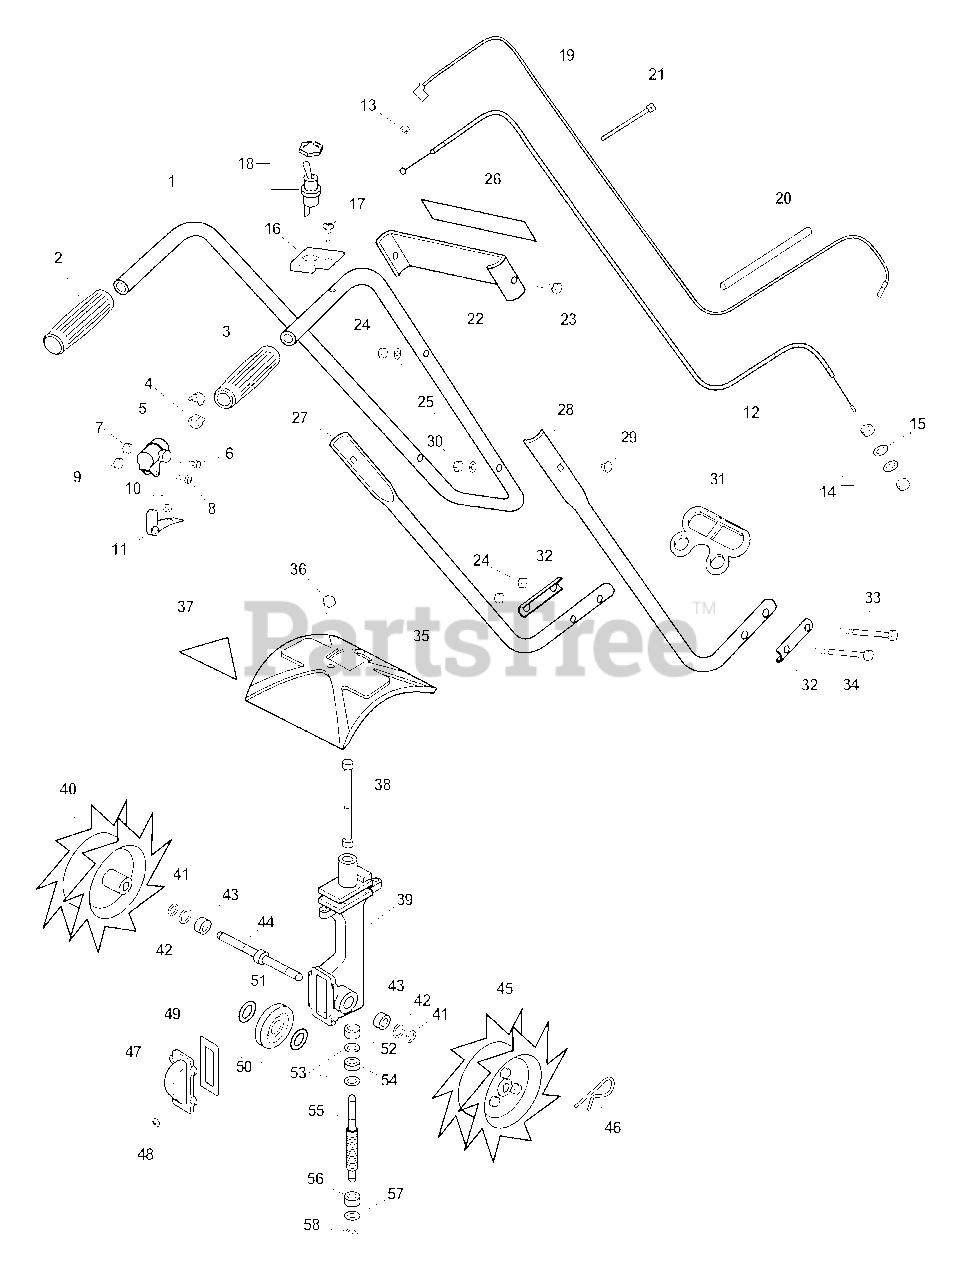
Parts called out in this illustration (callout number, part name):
1	HANDLE, UPPER
2	GRIP, HANDLE
3	GRIP, HANDLE
5	BRACKET, TRIGGER
7	NUT, LOCK M5
8	SCREW 5×25
9	NUT M5
11	TRIGGER, THROTTLE
12	CABLE, THROTTLE
13	RING, RETAINING - 7/32"
15	WASHER, LOCK 6 MM
16	BRACKET, SWITCH
17	SCREW 5×10
18	SWITCH, ON-OFF
19	LEAD - GROUND
21	TIE, CABLE
22	BRACKET, HANDLE
23	BOLT 1/4"×1-1/4"
24	NUT, LOCK 1/4
25	WASHER, SPRING
26	LABEL, CAUTION
27	HANDLE, LOWER
28	HANDLE, LOWER
31	HANDLE - FRONT
33	BOLT 1/4"×3"
34	BOLT 1/4"×3-1/4"
35	SHEILD, BLADE
36	BOLT 1/4"×1/2"
37	LABEL, CAUTION
38	SHAFT, DRIVE
39	CASE, GEAR
40	TINE, LEFT
41	RETAINER
43	BEARING, NEEDLE
45	TINE, RIGHT
46	PIN, SNAP
47	COVER, GEAR CASE
48	SCREW, TAPPING
49	GASKET, GEAR CASE
50	WASHER, THRUST 8
51	GEAR, WORM
52	BEARING, NEEDLE
54	BEARING, THRUST
55	GEAR, WORM
56	BEARING, ROLLER
58	RING, RETAINING
